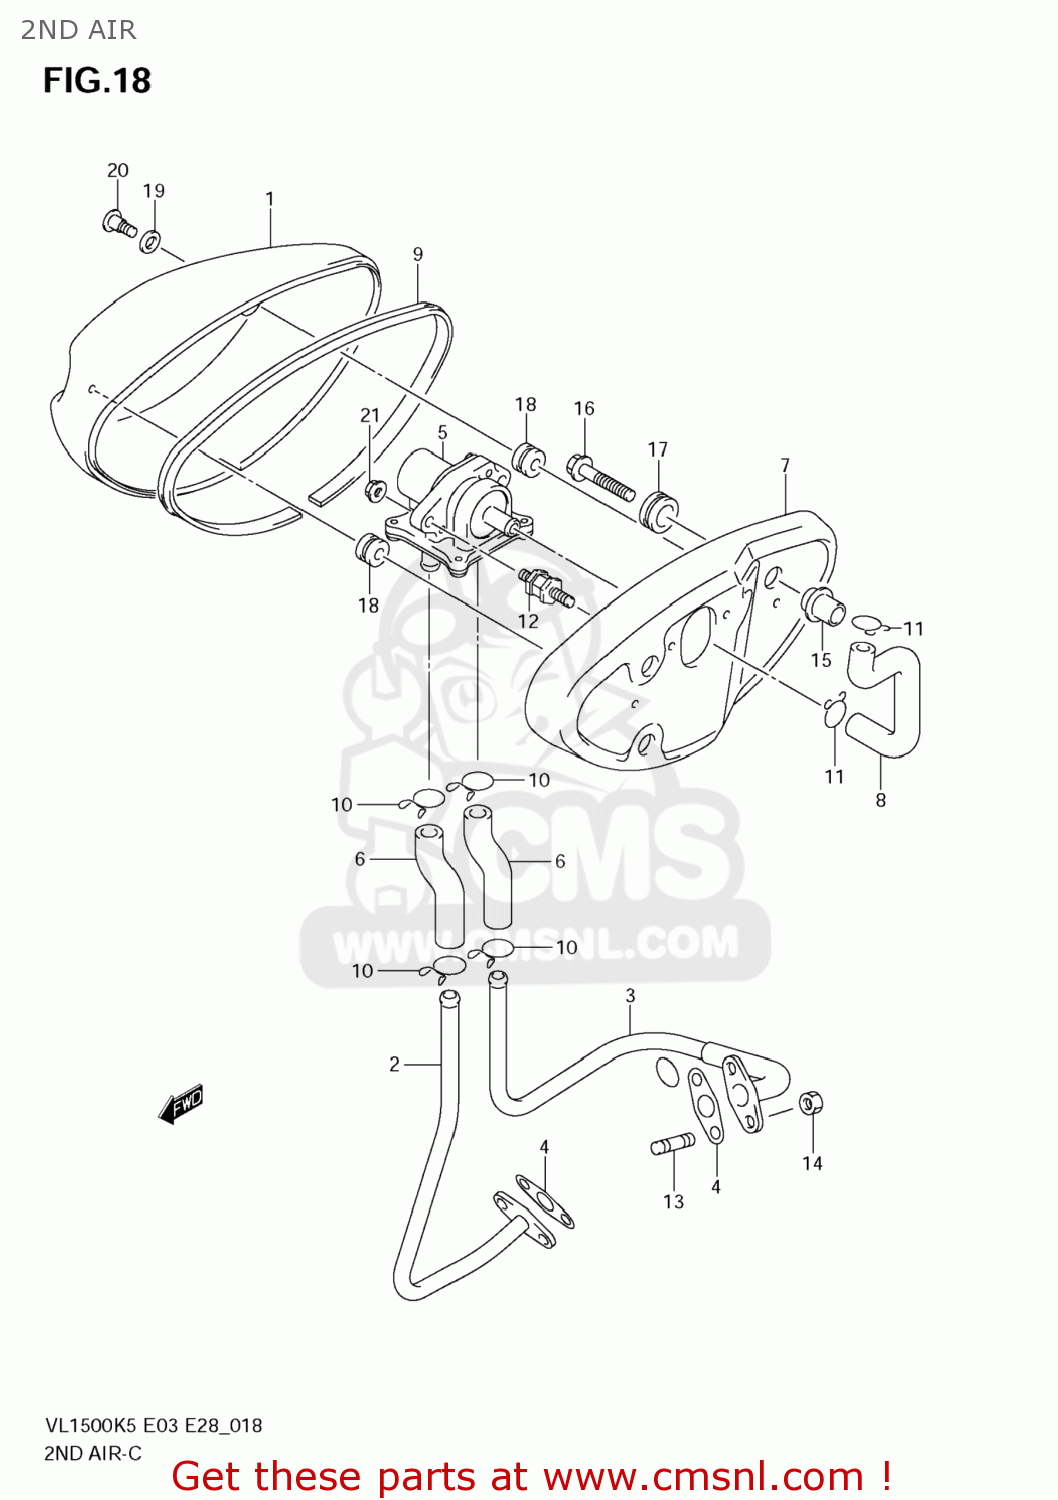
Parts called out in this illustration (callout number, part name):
1	COVER,2ND AIR
2	PIPE,2ND AIR FR
3	PIPE,2ND AIR RR
4	GASKET,2ND AIR PIPE (NAS)
5	VALVE ASSY,2ND AIR
6	HOSE,2ND AIR VALVE
7	BRACKET,2ND AIR SPRT
8	HOSE,2ND AIR CLEANER
9	CUSHION,2ND AIR COV
10	CLIP
11	CLIP
12	BOLT,CUSHION
13	BOLT,STUD
14	NUT
15	SPACER,2ND AIR SPRT
16	BOLT(6X37)
17	CUSHION
18	CUSHION
19	WASHER
20	SCREW(6X20)
21	NUT
